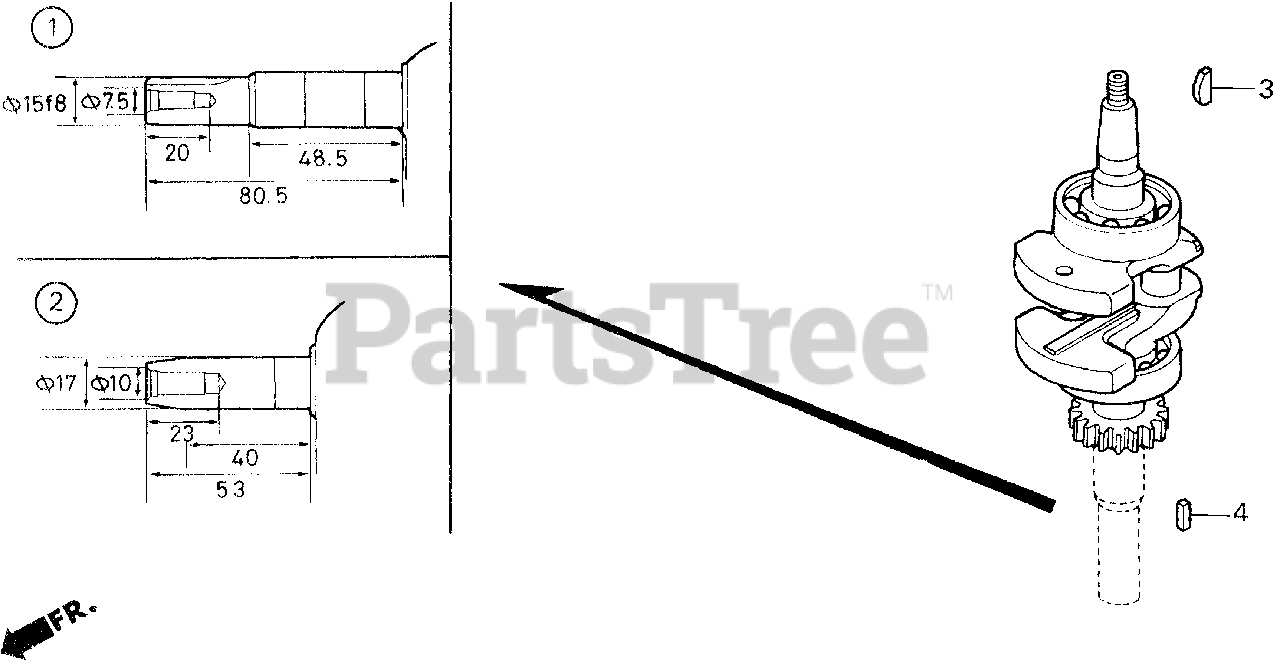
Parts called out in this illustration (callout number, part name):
1	CRANKSHAFT
3	KEY, SPECIAL
4	KEY (5MM)
